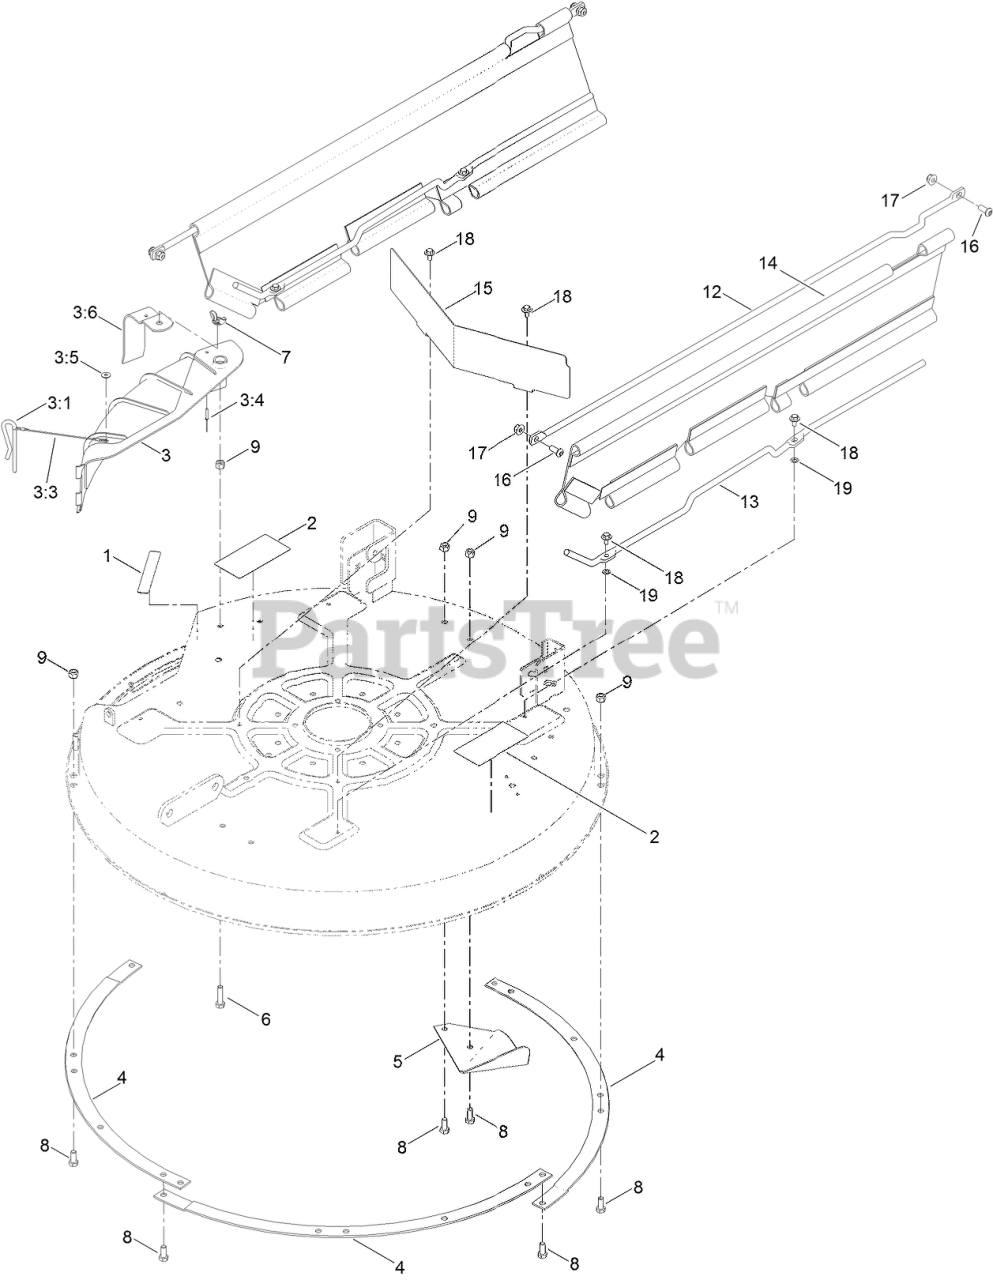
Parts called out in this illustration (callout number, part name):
1	DECAL-DANGER
2	DECAL-DANGER, DECK
3	DISCHARGE COVER ASM
3:1	PIN-LOCKING, CHUTE
3:3	LANYARD
3:4	RIVET-BLIND
3:5	WASHER-PLAIN
4	RING-DECK
6	SCREW-HH
7	NUT-WING
8	SCREW-HH
9	NUT-LOCK, NI
12	ROD-SUPPORT, UPPER
13	ROD-SUPPORT, LOWER
14	GUARD-SIDE
15	SHIELD-FRONT
16	SCREW-HSBH
17	NUT-HF, NI
18	SCREW-HHFTF
19	NUT-RETAINING
